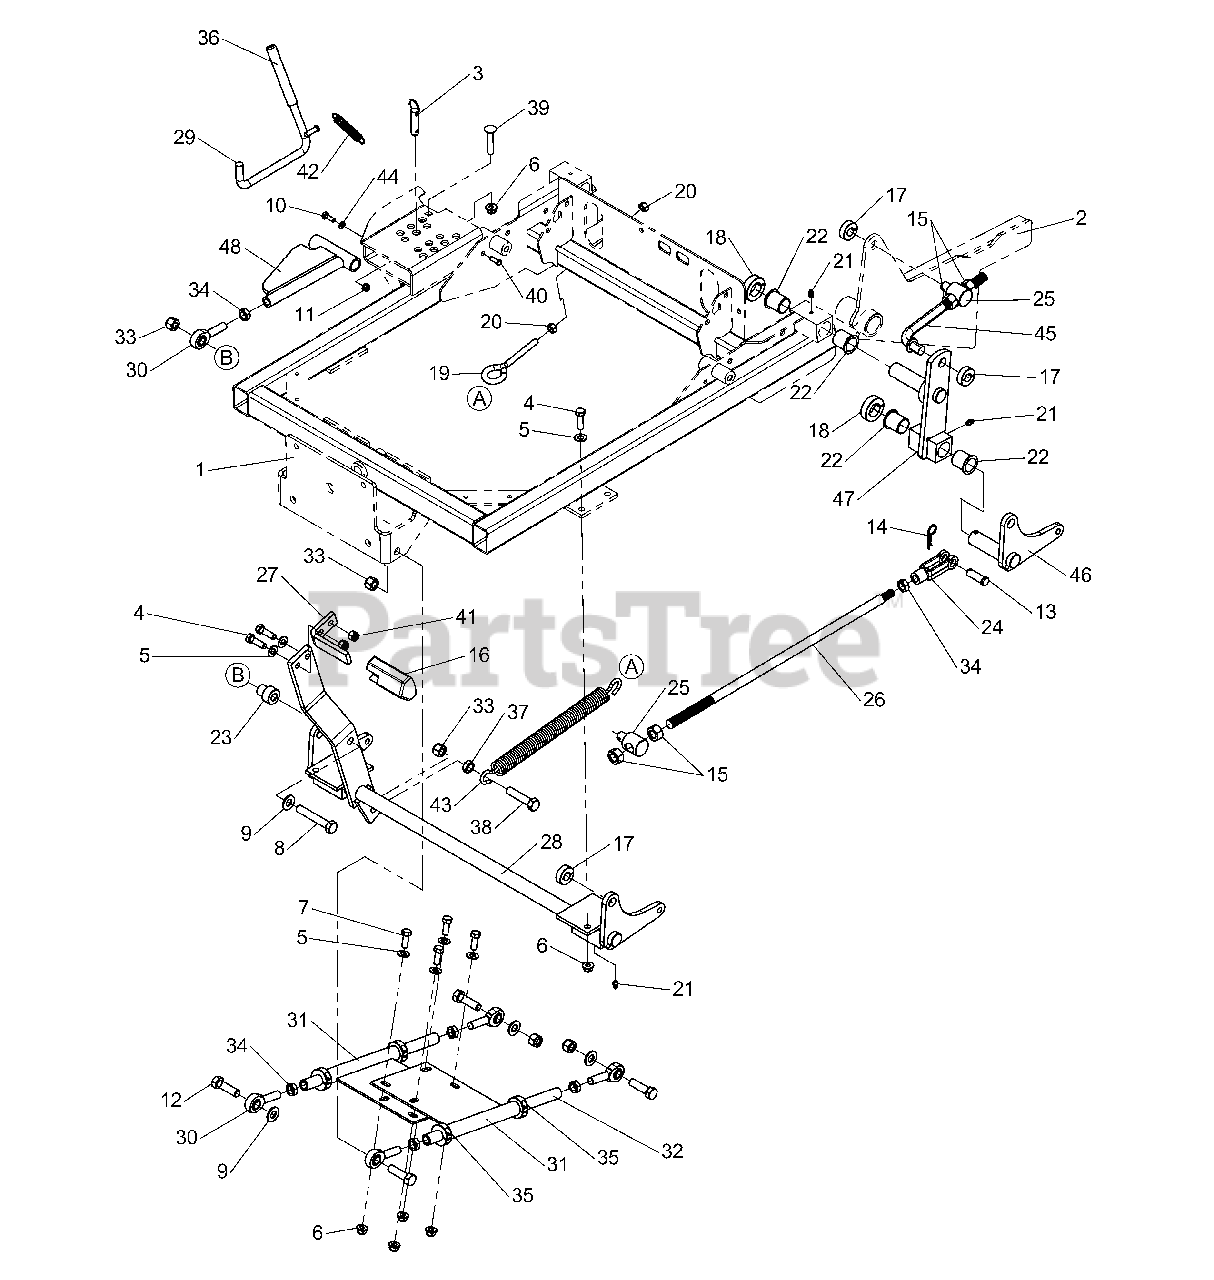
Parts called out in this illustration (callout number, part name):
1	MAIN FRAME (See Main Frame Group)
2	MOTOR MOUNT (See Rear Suspension Group)
3	HITCH PIN, 1/2 X 2"
4	BOLT, 3/8-16 X 1-1/4"
5	WASHER, 3/8" SAE
6	NUT, 3/8-16 Hex Nylock Flange
7	BOLT, 3/8-16 X 1"
8	BOLT, 1/2-13 X 3"
9	WASHER, 1/2" SAE
10	BOLT, 1/4-20 x 3/4"
11	NUT, 1/4-20 HEX NYLOCK FLANGE (5025391)
12	BOLT, 1/2-13 X 1-3/4"
13	CLEVIS PIN, 1/2" X 1-1/2"
14	HAIR PIN CLIP
15	NUT, 5/8-11 HEX
17	COLLAR, 5/8" Split
18	COLLAR, 1" Split
19	EYE BOLT, 3/8-16 X 5"
20	NUT, 3/8-16 Hex
21	GREASE FITTING
22	BUSHING, Flange
23	ADAPTER, CASTER AXLE
24	CLEVIS , 1/2-20, STEEL
25	SPRING ROD PIVOT
26	DECK ADJUSTMENT ROD
27	PEDAL, FOOT - BLK
28	DECK LIFT SHAFT
29	WELD, ROD DECK LIFT - BLK
30	BALL JOINT, 1/2-20 Male
31	DECK STABILIZER
32	DECK STABILIZER SHAFT
33	NUT, 1/2-13 Hex Nylon Lock
34	NUT, 1/2-20 Hex Jam
35	COLLAR, 3/4" Split
37	NUT, 1/2-13 Hex Jam
38	BOLT, 1/2-13 X 2-1/4"
39	CARRIAGE BOLT, 3/8-16 X 2"
40	CLEVIS PIN, 1/4" x 3/4"
41	NUT, 3/8-16 Hex Nylon Lock
42	SPRING, Extension
43	DECK LIFT SPRING
44	WASHER, 1/4 SAE (5025154)
45	DECK LIFT ROD
46	DECK LIFT PIVOT, LH (Shown)
47	REAR DECK LIFT, LH (Shown)
48	DECK ADJUST LINK
